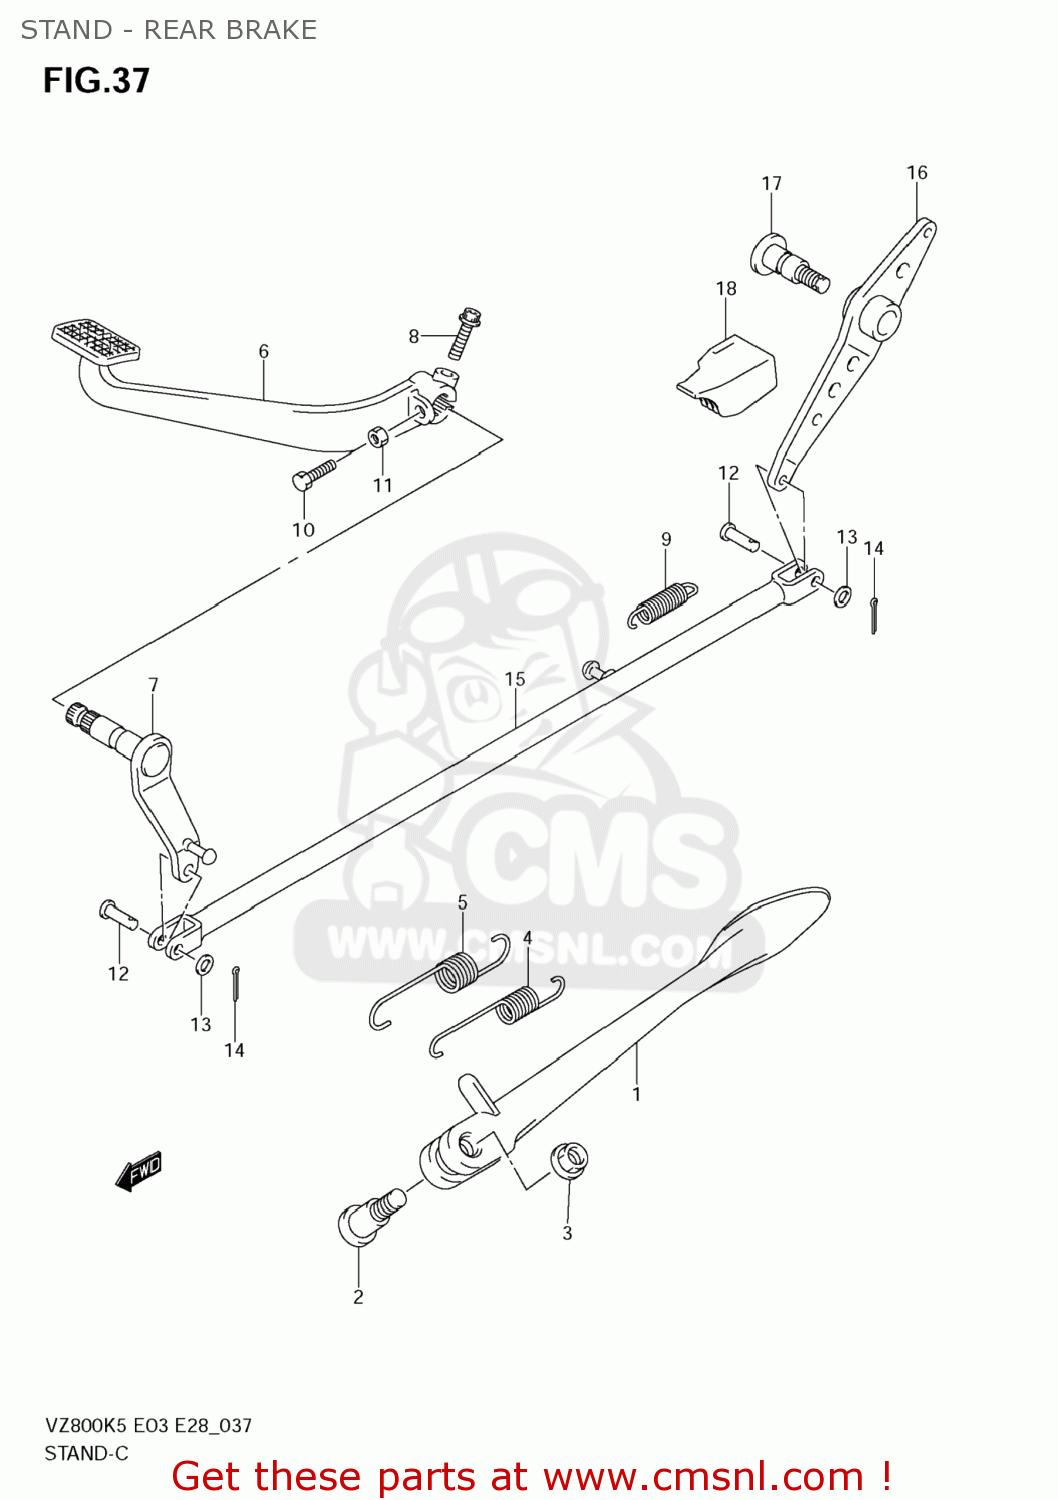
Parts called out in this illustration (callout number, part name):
1	STAND,PROP
2	BOLT(10X37.5)
3	NUT,PROP STAND
4	SPRING
5	SPRING
6	PEDAL,BRAKE
7	ARM,BRAKE ROD
8	BOLT
9	SPRING
10	BOLT
11	NUT
12	PIN
13	WASHER
14	PIN
15	ROD,RR BRAKE FR
16	LINK,RR BRAKE
17	SHAFT,BRAKE PEDAL
18	RUBBER,BRAKE LINK
